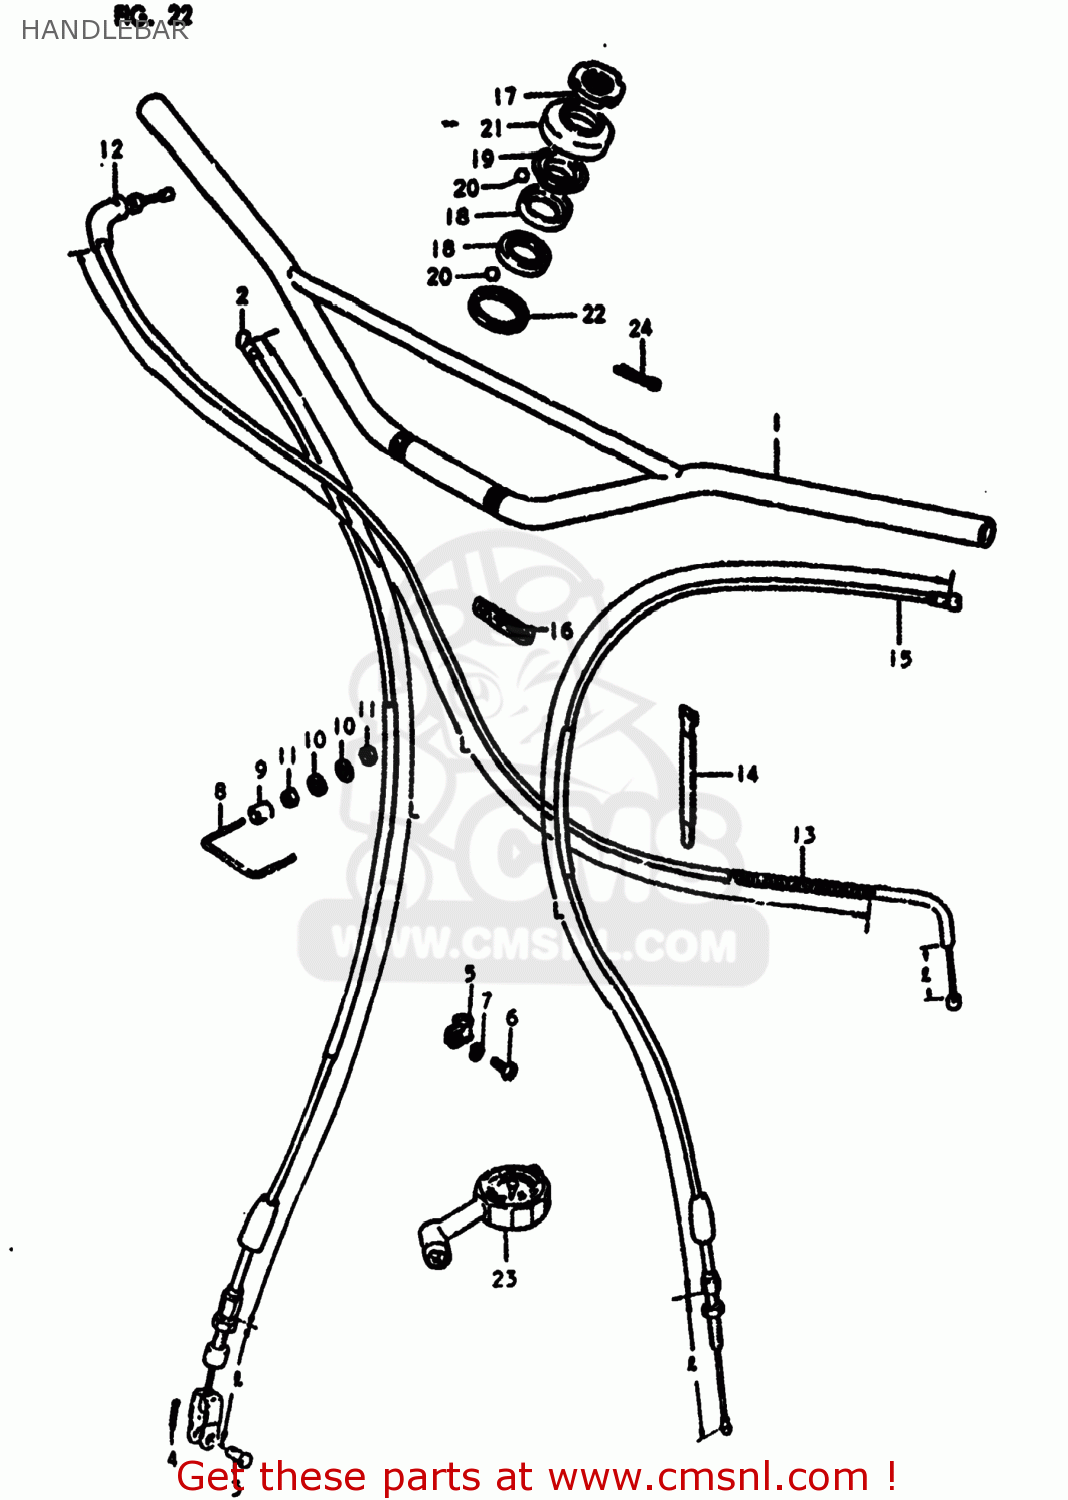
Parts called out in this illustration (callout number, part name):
1	HANDLEBAR
2	CABLE ASSEMBLY,FRONT BRAKE
3	PIN(L:17.5)
4	PIN
5	GUIDE,CABLE
6	SCREW
7	LOCK WASHER
8	CLAMP,CABLE
9	BUSHING
10	WASHER
11	NUT 3MM
12	CABLE ASSEMBLY,THROTTLE
13	PROTECTOR,CABLE
14	CLAMP
15	CABLE ASSY,CLUTCH
16	CLAMP L:35
17	NUT,STEERING STEM
18	RACE,STEERING,INNER,UPPER
19	RACE,STEERING,OUTER,UPPER
20	BALL
21	SEAL,STEERING UPR DUST
22	DUST SEAL,STEERING HEAD
23	GAUGE ASSY,AIR PRESSURE
24	PIN 20X20
